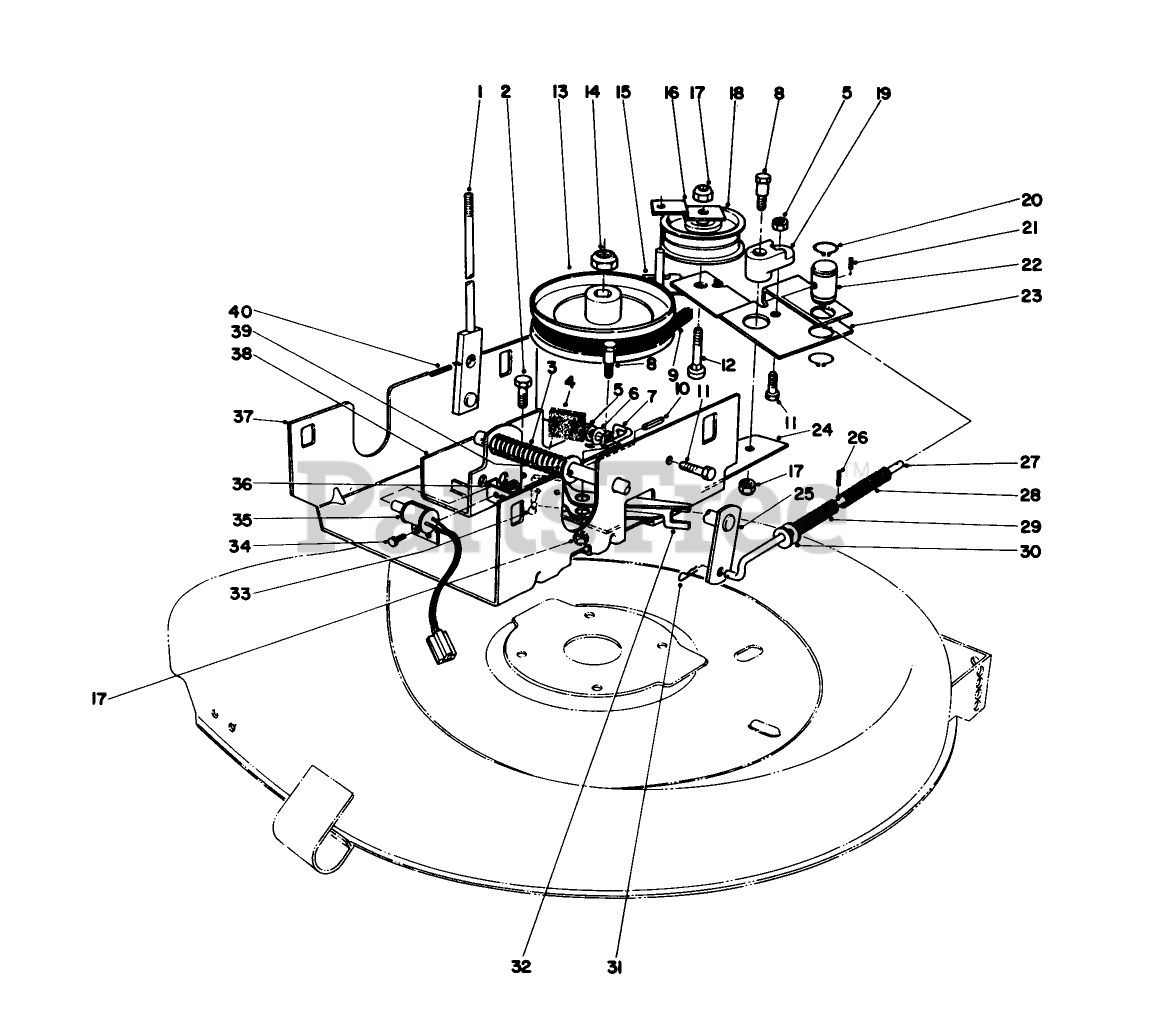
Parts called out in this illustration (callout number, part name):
2	SCREW-HH
4	PAD-BRAKE
5	NUT-LOCK, NI
6	WASHER-FLAT
8	SHOULDER BOLT
9	V-BELT
10	PIN-SPRING
11	SCREW-HH
12	SCREW-CARR
14	NUT-LOCK, NI
17	NUT-LOCK, NI
18	PULLEY-IDLER
20	RING-RETAINING
21	PIN-ROLL
26	PIN-SPRING
31	PIN-COTTER
36	NUT-KEPS
39	WASHER-FLAT
